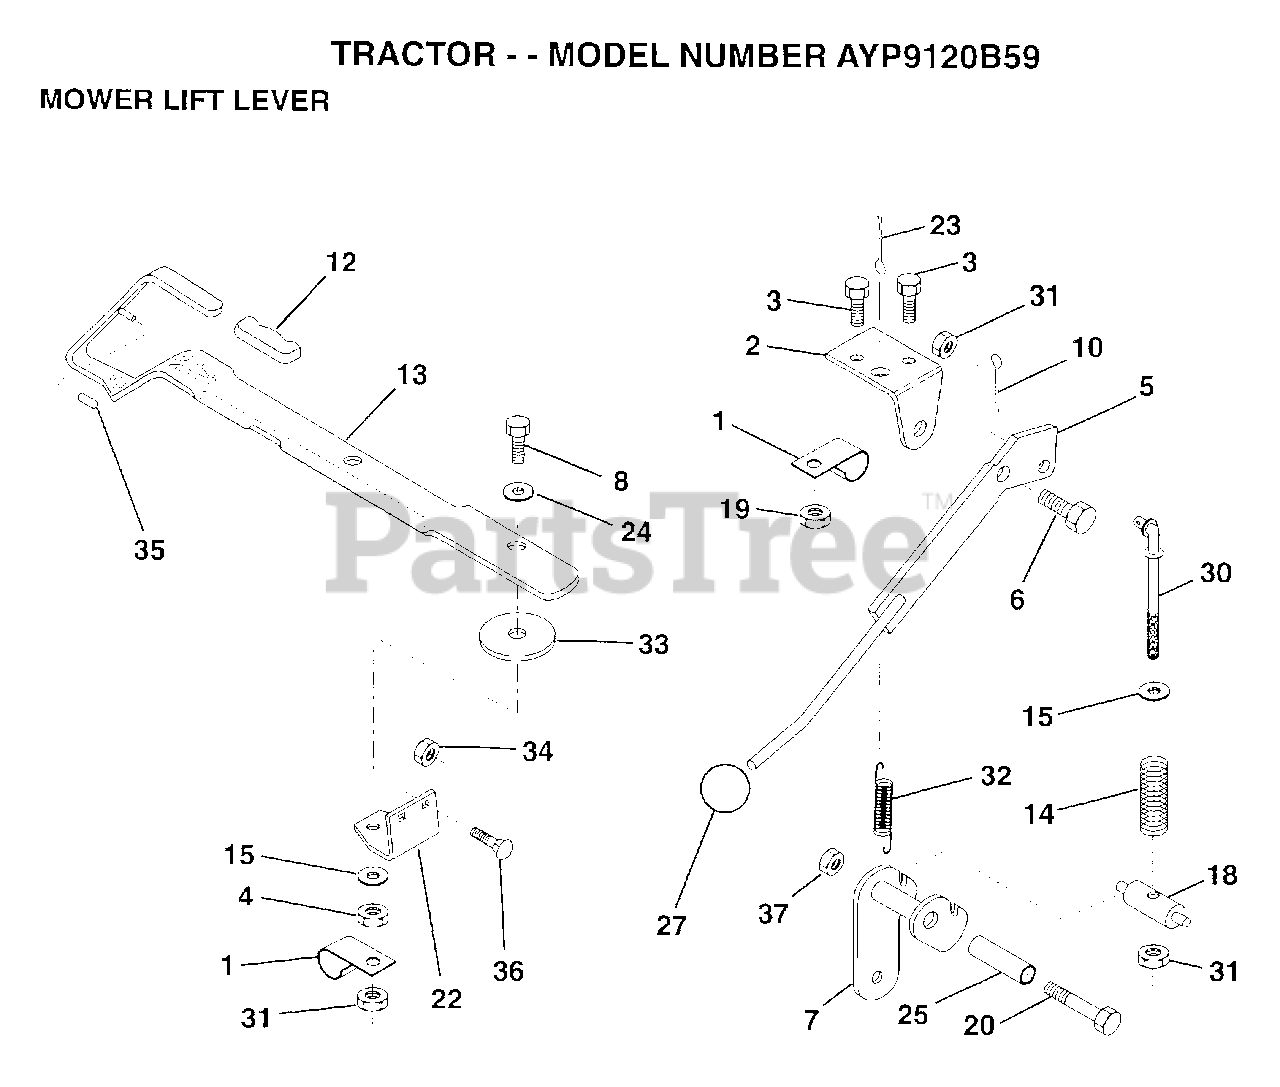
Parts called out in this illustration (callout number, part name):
1	"CLIP,INSULATOR"
2	BRKT CLUTCH
3	BOLT HXHD FIN
4	NUT
5	LEVER.ASM.CLUTCH
6	"BOLT, SHOULDER LT"
7	ARM.CLUTCH.ASM
8	BOLT
10	COTTER PIN
12	GRIP HANDLE
13	LEVER LIFT LR
14	COMP CLUTCH SPRNG
15	WASHER HYT
18	TRUNNION
20	BOLT
22	LIFT LEVER BRKT
24	WASHER
25	TUBE SPACER
27	KNOB T(3/8 HOLE)
30	ROD TENSION CLUTC
31	LOCKNUT
32	SPRING EXT
33	WASHER
34	NUT
35	VINYL CAP RED
36	BOLT
